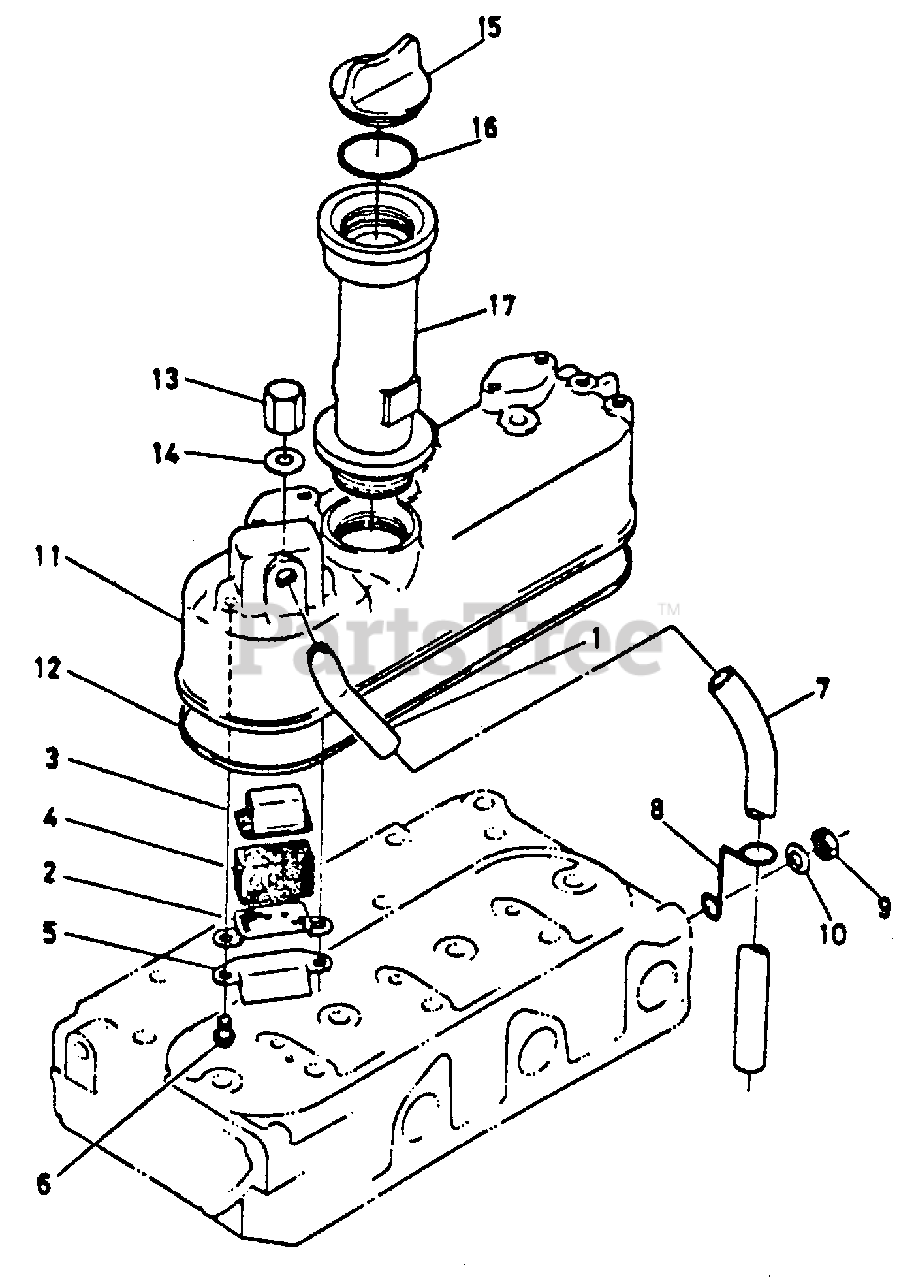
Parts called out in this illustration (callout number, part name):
1	Joint, Breather Pipe
2	Plate, Breather Element 1
3	Plate, Breather Element 2
4	Element, Breather
5	Shield, Breather Oil
6	Screw, M5 X 10MM Class 4.8 P/Hdcr
7	Tube, Breather
9	Nut, M8 Class 8
10	Washer, 8.8 X 17 X 1.6MM
12	Gasket, Head Cover
15	Plug, Filler
17	Extension, Oil Fill
